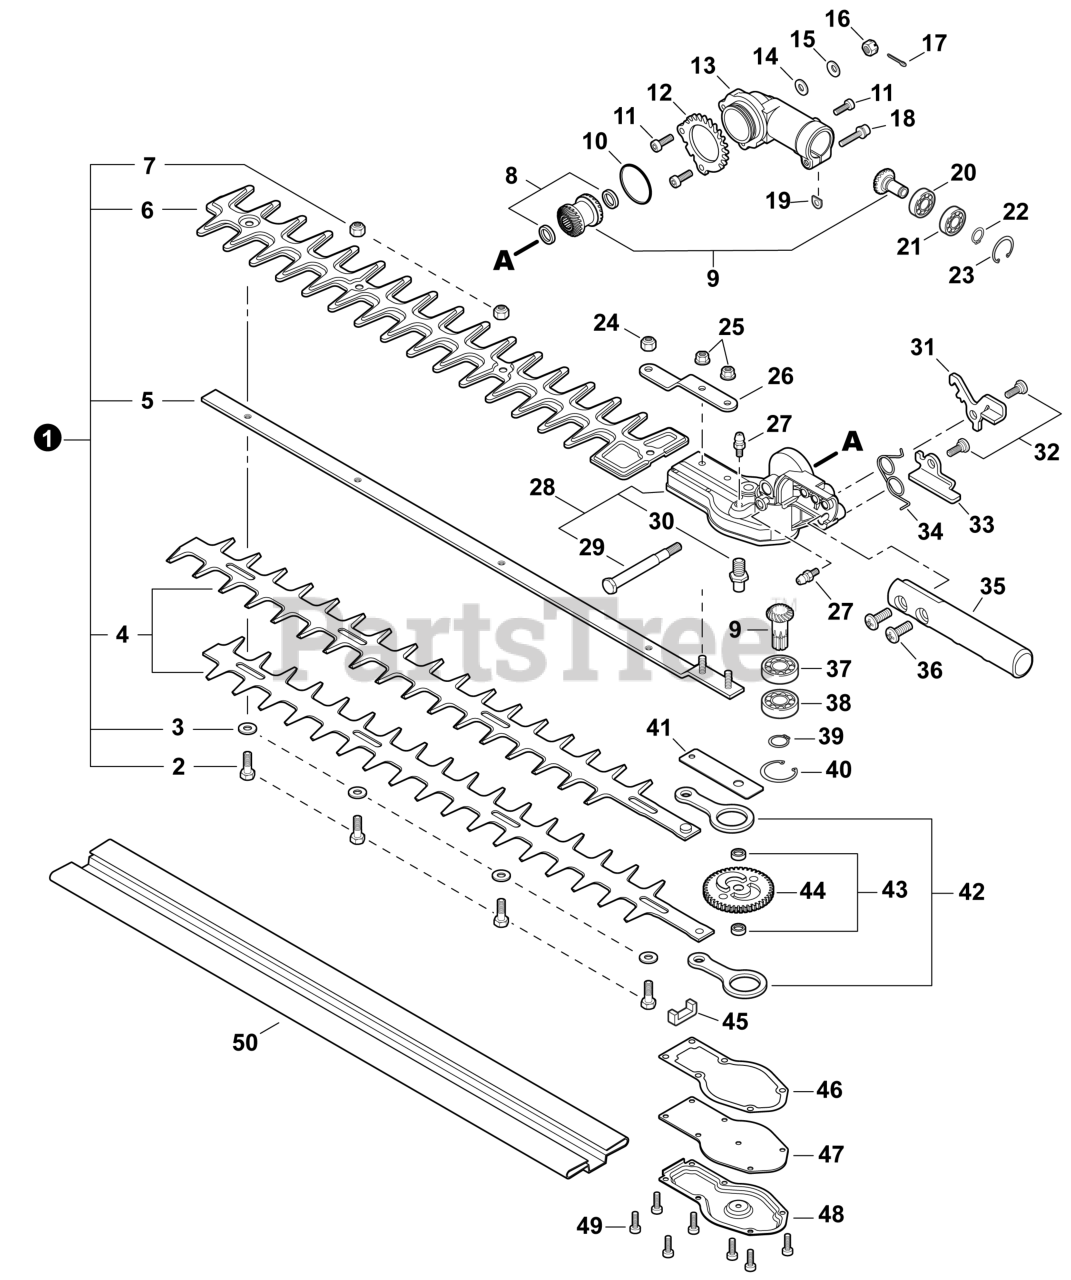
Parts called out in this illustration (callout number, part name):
1	CUTTER ASSY, 22"
2	BOLT M6x20
3	WASHER M6
4	CUTTER 22"
5	GUIDE BAR 22"
6	GUARD, CUTTER BLADE
8	COLLAR ?16x?10xL= 2
9	GEAR SET
11	BOLT 5x12
12	RING, LOCKING
13	HOUSING, UPPER GEAR CASE
14	WASHER 6.5x13x1
15	WASHER, CONE M6
17	PIN, COTTER ?1.6x15
18	BOLT M5x25
19	D-WASHER
20	BEARING, BALL 609
21	BEARING, BALL 609ZZ
22	RING, SNAP ?9
23	RING, SNAP 24
25	NUT, FLANGE M5
26	BRACKET, CUTTER
27	FITTING, GREASE
28	HOUSING ASSY, GEAR CASE
30	MAINSHAFT
31	LEVER, LOCK
32	BOLT M6
33	RELEASE, LOCK
34	SPRING, TORSION
35	LEVER, ADJUSTMENT
36	SCREW, TRUSS M6x20
37	BEARING, BALL 6001
38	BEARING, BALL 6001ZZ
39	RING, SNAP ?12
40	RING, SNAP 28
41	PLATE, GUIDE
43	SPACER ?11x?8x3.4
44	GEAR, CAM
45	PACKING, FELT
46	GASKET, GEAR CASE
48	COVER, GEAR CASE
49	BOLT 4x10
50	SCABBARD
